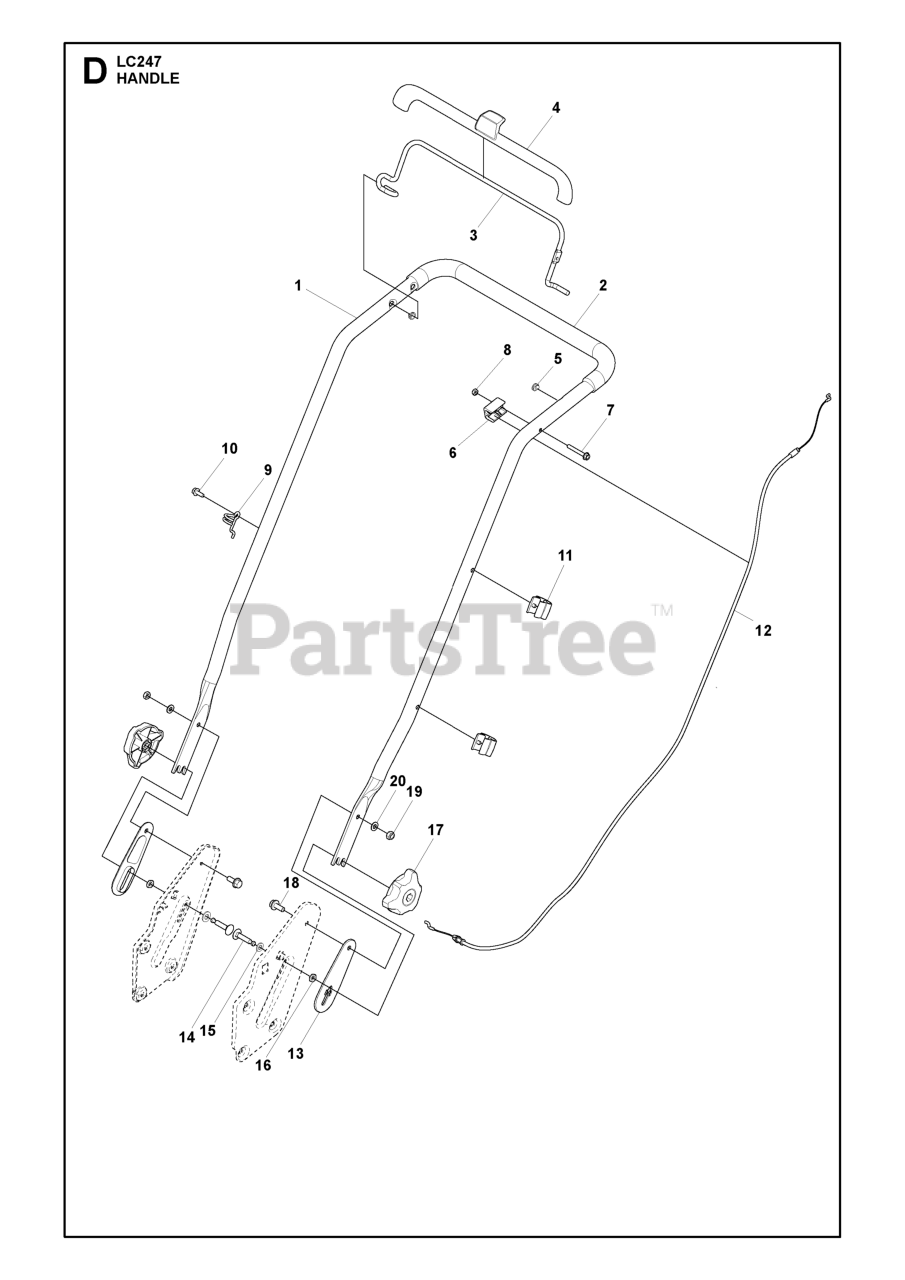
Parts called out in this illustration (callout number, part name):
8	NUT FLANGE - M6
10	SCREW
16	NUT ML6M M8
19	LOCKNUT M8
